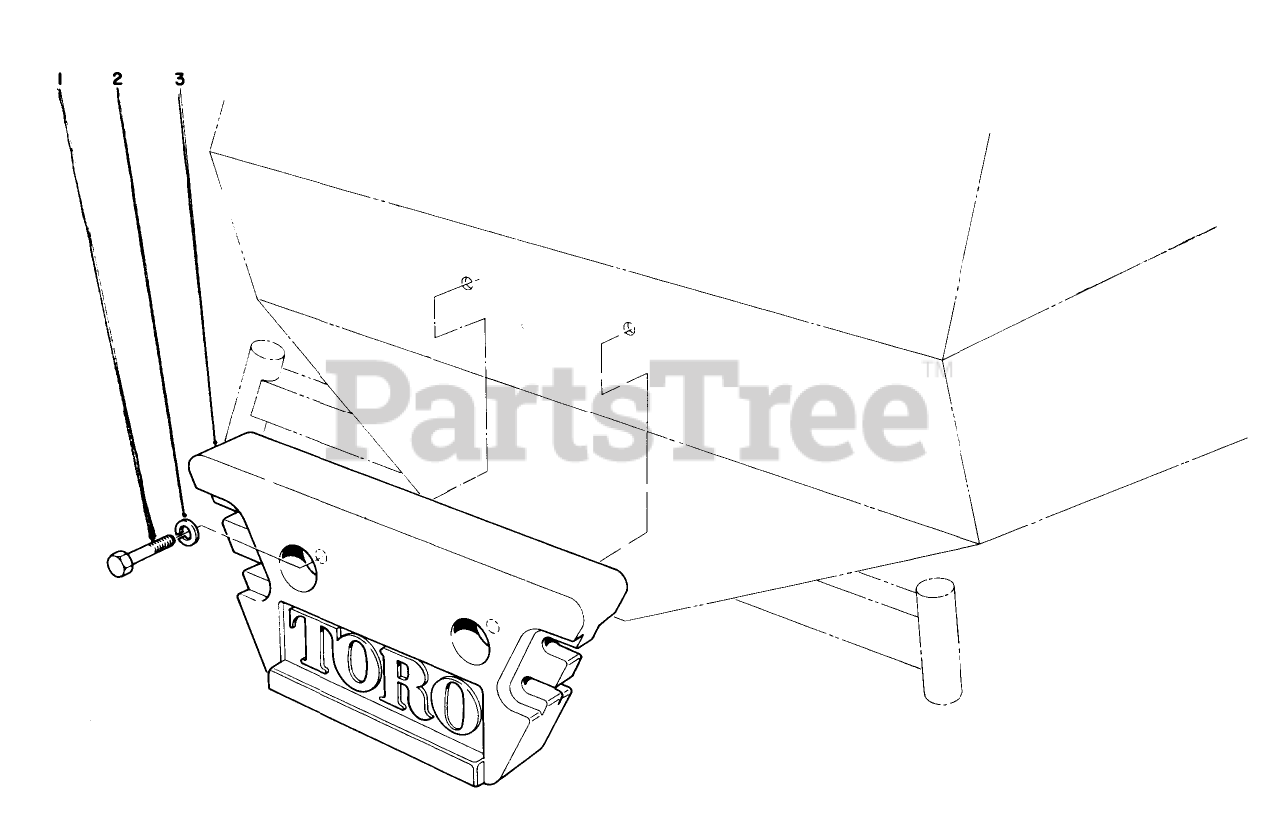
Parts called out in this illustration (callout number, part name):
1	WEIGHT-REAR
2	SCREW-HH
3	WASHER-LOCK
